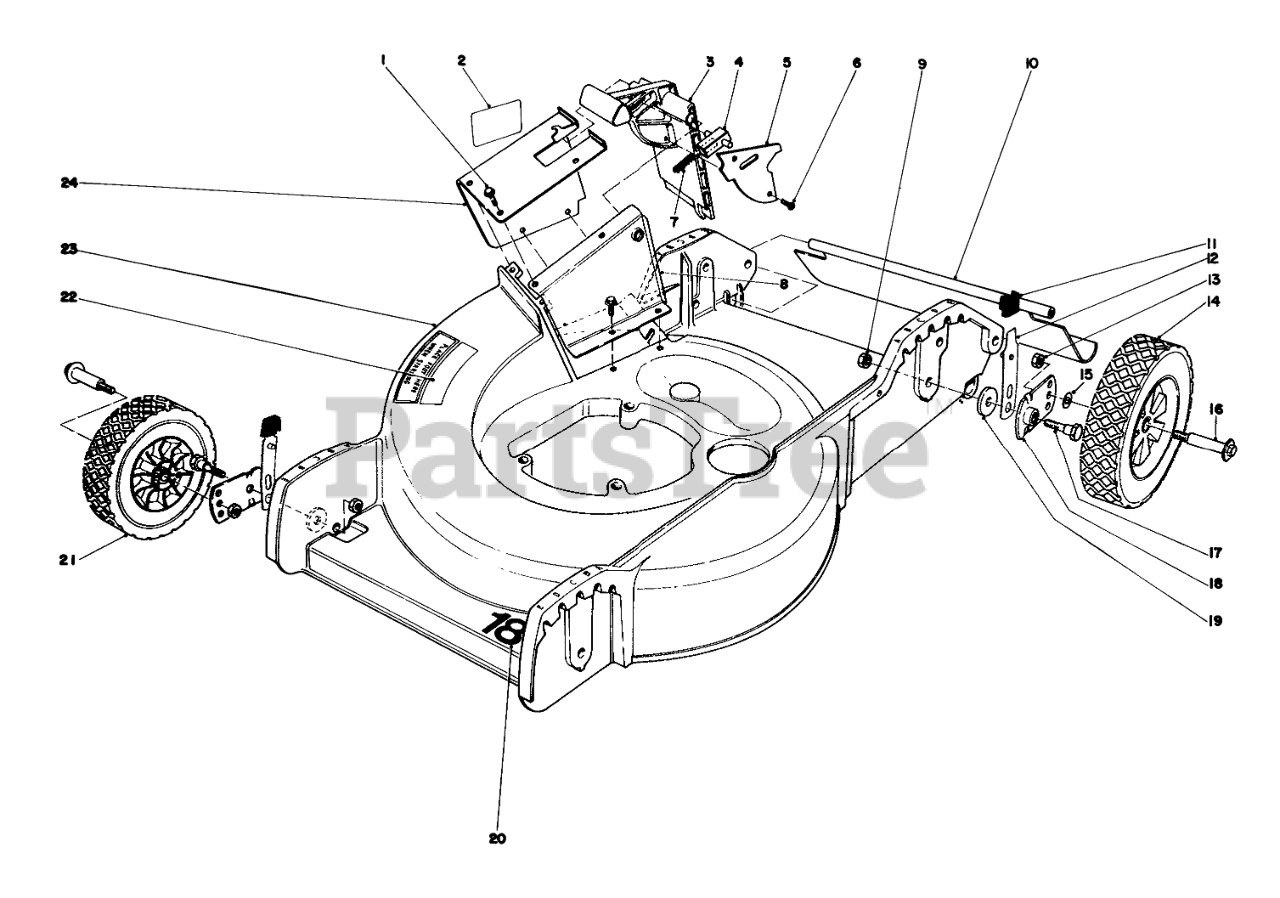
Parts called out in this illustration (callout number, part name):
1	SCREW
2	Decal-Danger
3	PUMP-COOLER HOSE
4	Door Latch
5	Door Cover
7	Latch Spring
8	Inner Tunnel
9	Nut
10	SHIELD - TRAILING
11	KNOB-ARM
12	SPRING ARM ASM
13	Nut
14	WHEEL TIRE ASM 8 IN
15	WASHER
16	BOLT-WHEEL
17	PIVOT SCREW
18	PIVOT ARM ASSY
19	Pivot Washer
20	Decal
21	WHEEL TIRE ASM 7 IN
22	Decal-Place Foot Here
23	Housing
24	Tunnel Outer
